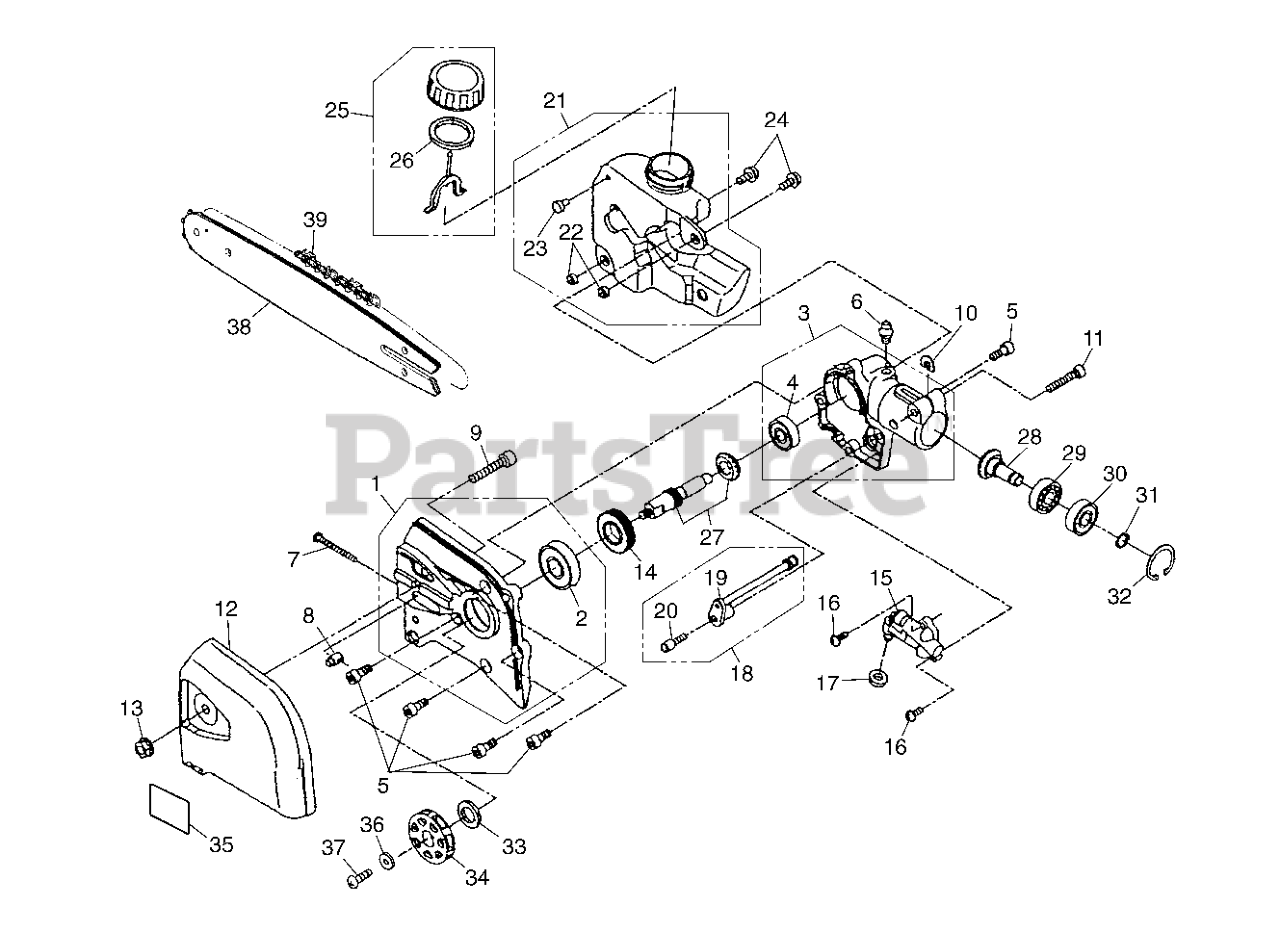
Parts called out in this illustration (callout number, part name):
1	CASE L-COMP
3	GEARCASE COMP (RIGHT)
5	BOLT, M5 x 12
6	FITTING, GREASE
9	BOLT, M6 x 30
11	BOLT
12	COVER, CHAIN
14	GEAR, WORM
15	PUMP ASSY, OIL
16	SCREW, M4 x 10
18	PIPE ASSY, OIL
19	PIPE, OIL
21	TANK ASSY,OIL(RPLS T307313800)
24	SCREW, M5 x 12
25	CAP ASSY, OIL
26	GASKET, OIL CAP
27	SHAFT, GEAR
28	GEAR, BEVEL
31	RING, SNAP (RPLS T330013330)
34	SPROCKET
35	LABEL (PSZ2500)
38	USE PSZ12
39	Saw Chain, 12" Polesaw
